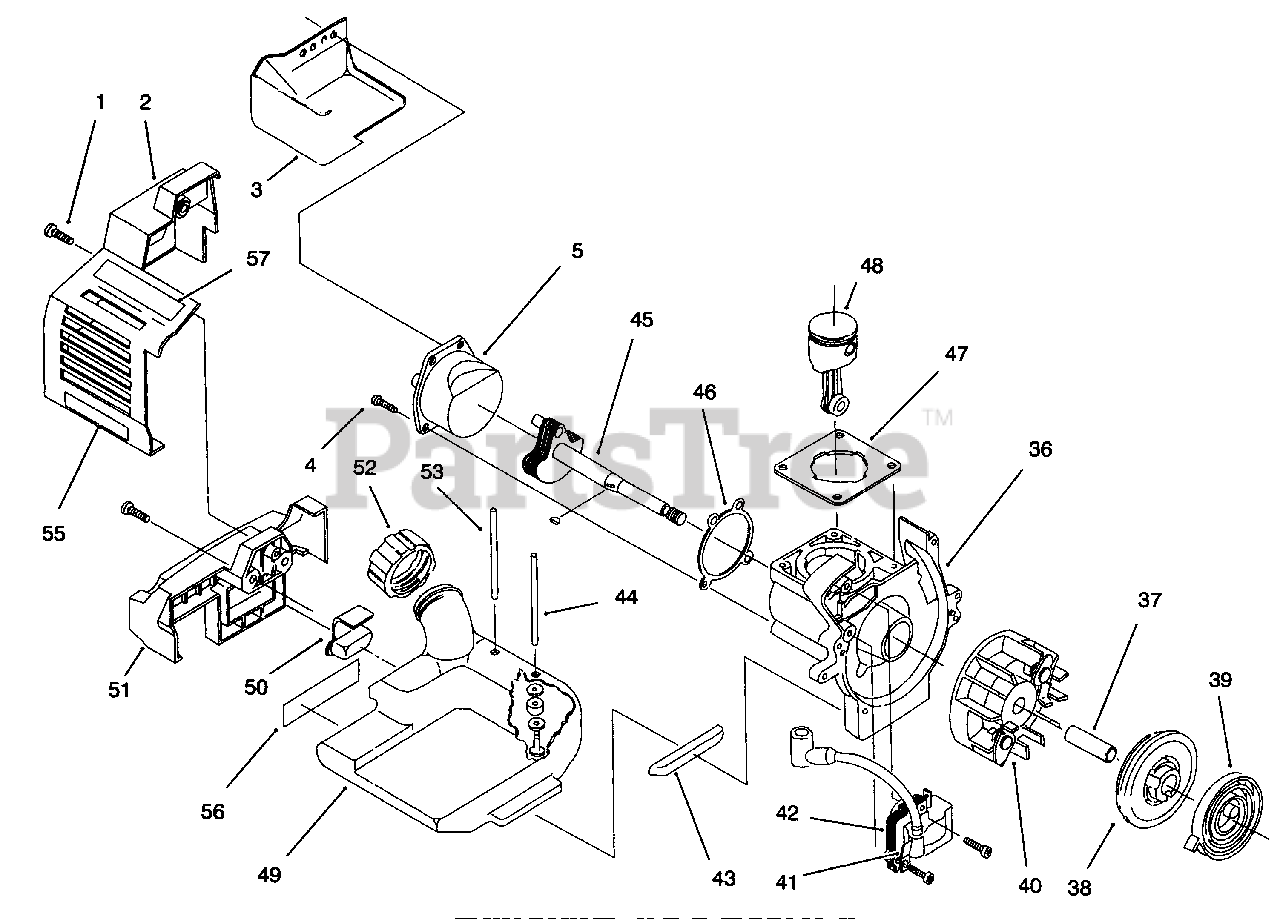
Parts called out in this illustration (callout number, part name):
2	Rear Cover
3	Heat Shield
4	Mounting Screw
5	Crankcase Cap
36	Crankcase Asm. (Incl. Ref. #5, 45-46)
38	Recoil Pulley
39	Recoil Spring
40	Flywheel Asm.
41	Ground Tab
42	Module Asm.
43	Front Pad-Fuel Tank
44	Fuel Line Asm.
45	Power Shaft Asm.
46	Crankcase Cap Gasket
47	Cylinder Gasket
48	Piston and Rod Asm.
49	Fuel Tank Asm.
50	Rear Fuel Tank Pad
51	Fuel Tank Bracket
52	Fuel Tank Cap
53	Return Fuel Line
55	Decal-Warning
56	Decal-Fuel & Oil Mix
57	Decal-Carb.
